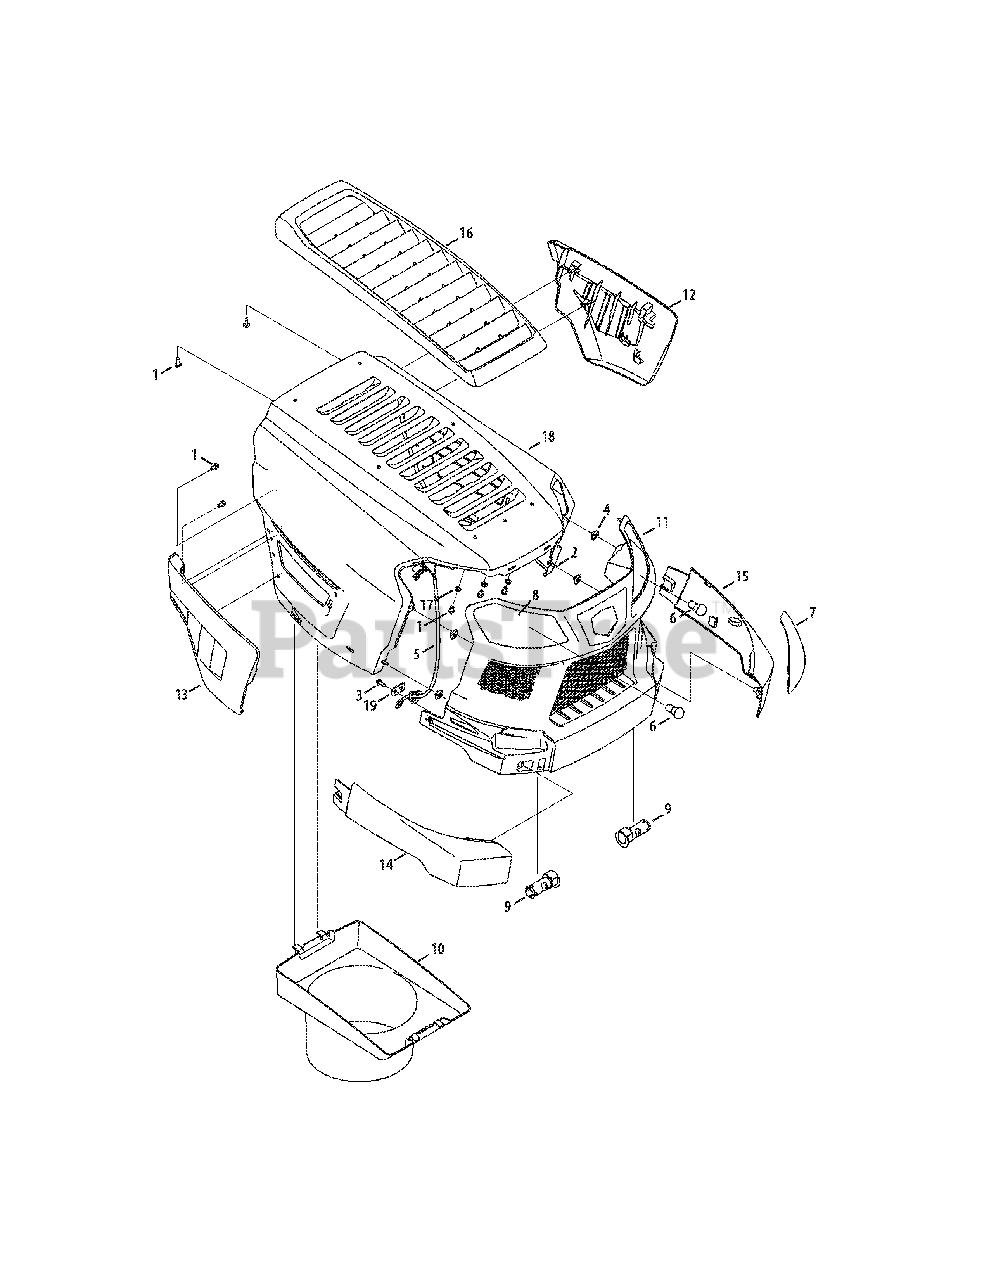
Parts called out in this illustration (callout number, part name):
1	Screw, 1/4-15 x 0.50
2	Hex Cap Screw, 1/4-20 x .625
3	Screw, 1/4 x .750
4	Nut, 1/4-20, .433 x .170
5	Headlight Harness
6	Miniature lamp 12V socket
7	Grill Lens - LH
8	Grill Lens - RH
9	Hood Pin
12	Side Cover, LH
13	Side Cover, RH
14	Grill Panel, RH
15	Grill Panel, LH
16	Hood Scoop
17	Flat Washer, .281 x .500 x .063
18	Hood
19	Harness Bracket
